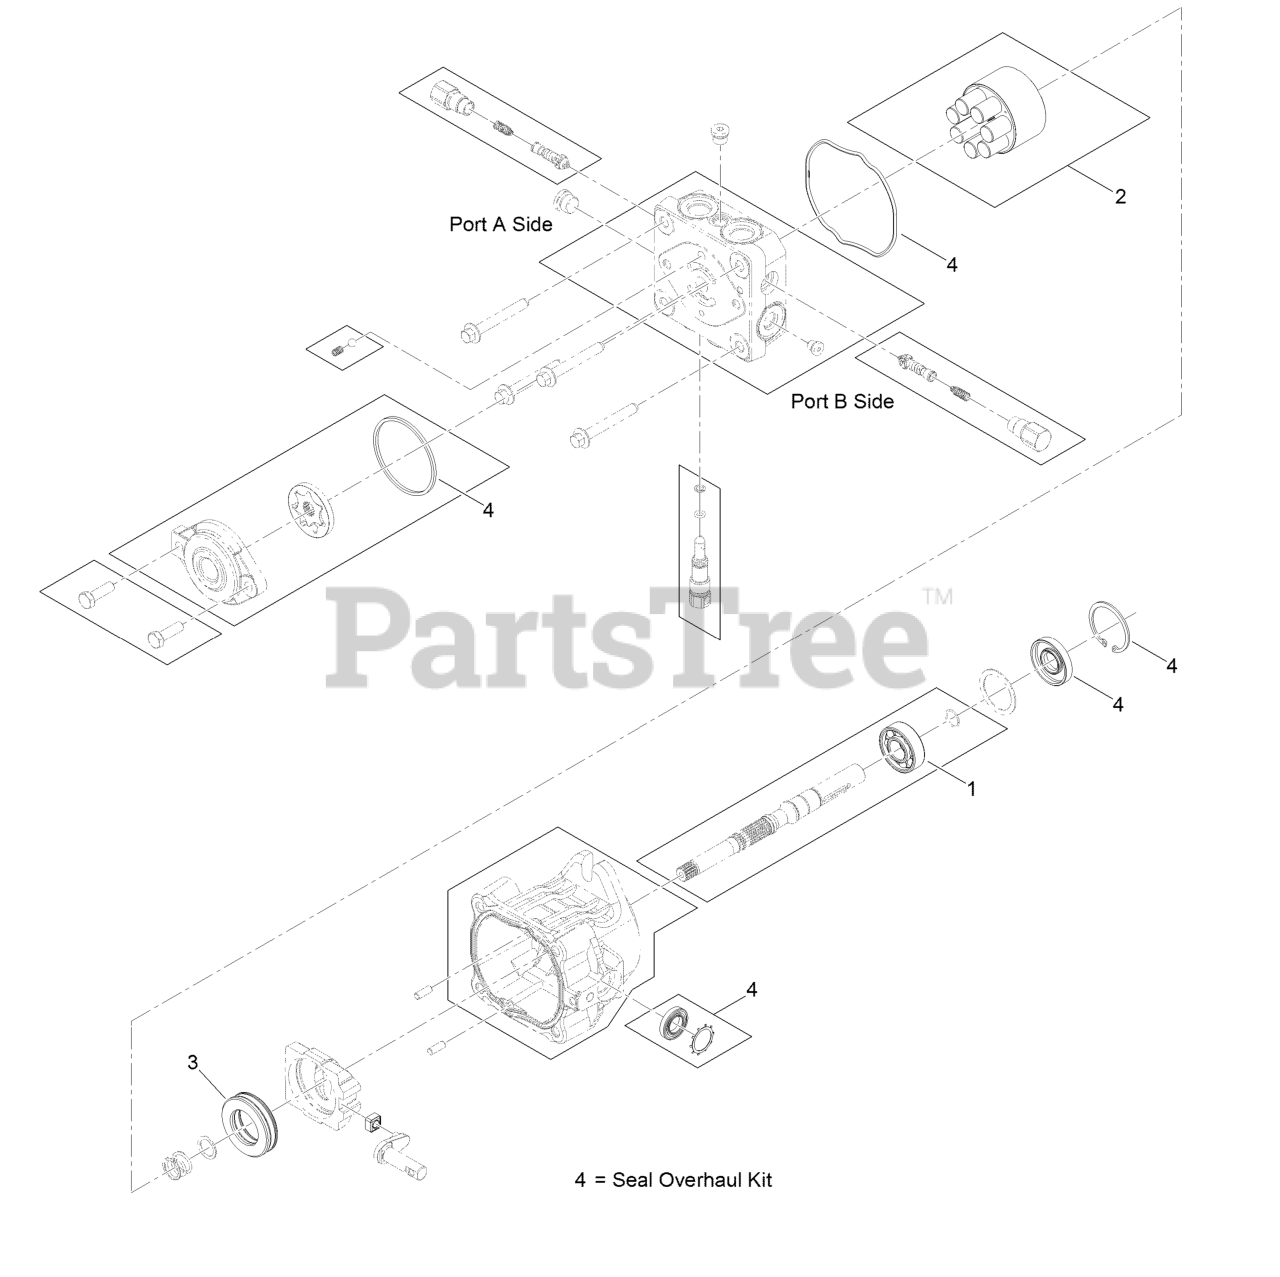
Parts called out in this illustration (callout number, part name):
1	Bearing-Ball
2	Cylinder Block Kit
3	Bearing-Thrust, Plastic Cage
4	Seal Overhaul Kit
